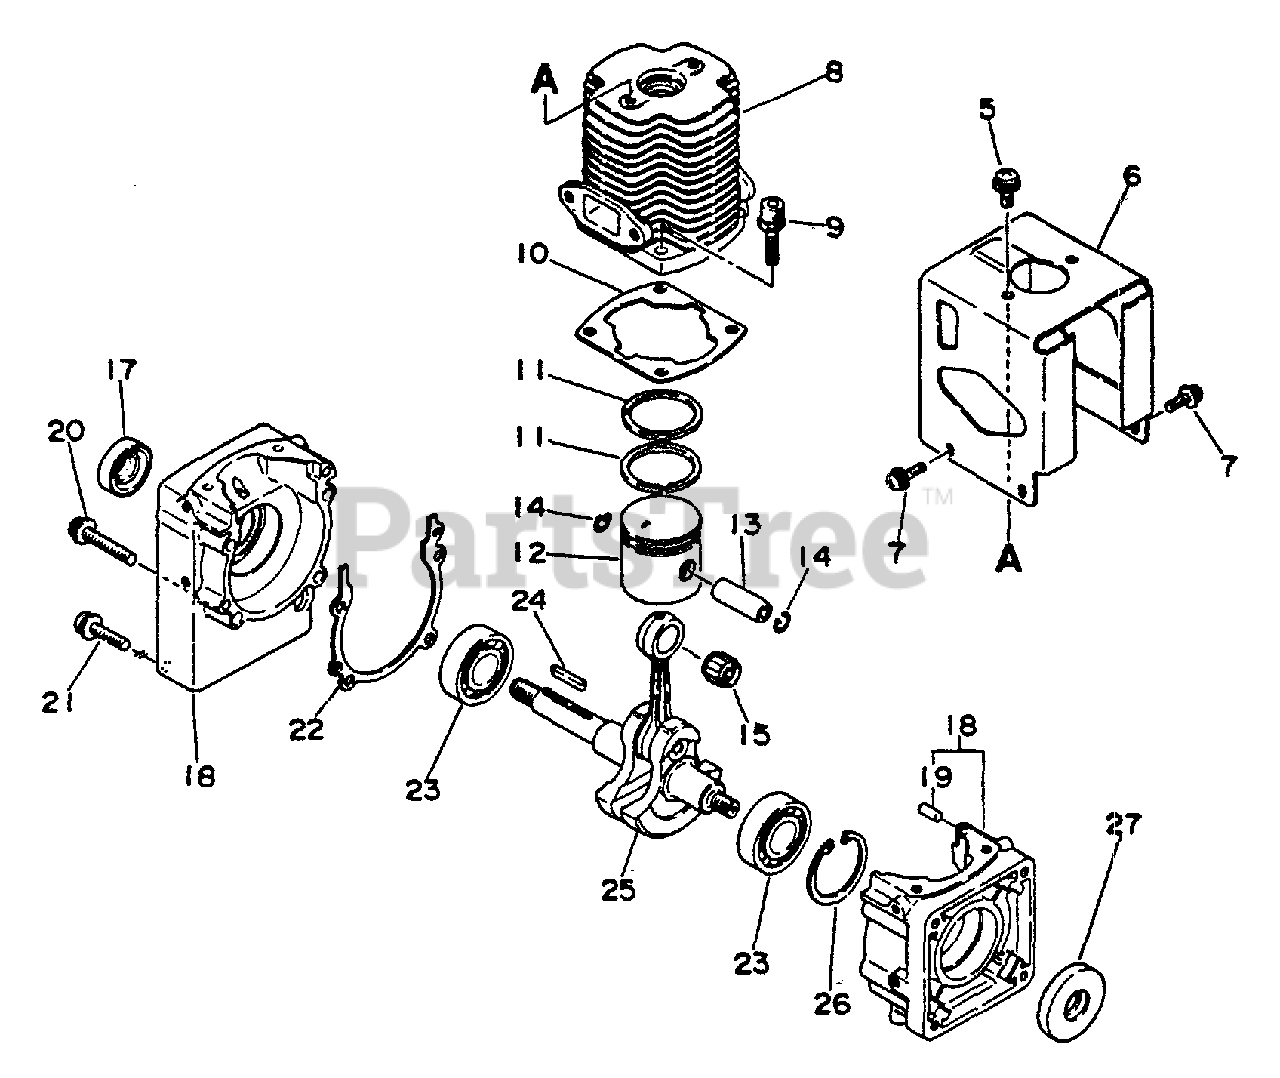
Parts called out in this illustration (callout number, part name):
5	SCREW - 5X10
6	SHIELD, CYLINDER
7	SCREW - 4X14
8	CYLINDER
9	SCREW - 5X20
10	GASKET, CYLINDER
11	RING, PISTON
12	PISTON
13	PIN, PISTON
14	RING, RETAINING - 8
15	BEARING, NEEDLE
17	SEAL, OIL
18	CRANKCASE KIT
19	PIN - LOCATING
20	SCREW - 5X30
21	SCREW - 5X20
22	GASKET, CRANKCASE
23	BEARING, BALL - 6202
24	KEY
25	CRANKSHAFT ASSY
26	RING, RETAINING - 35
27	SEAL, OIL
